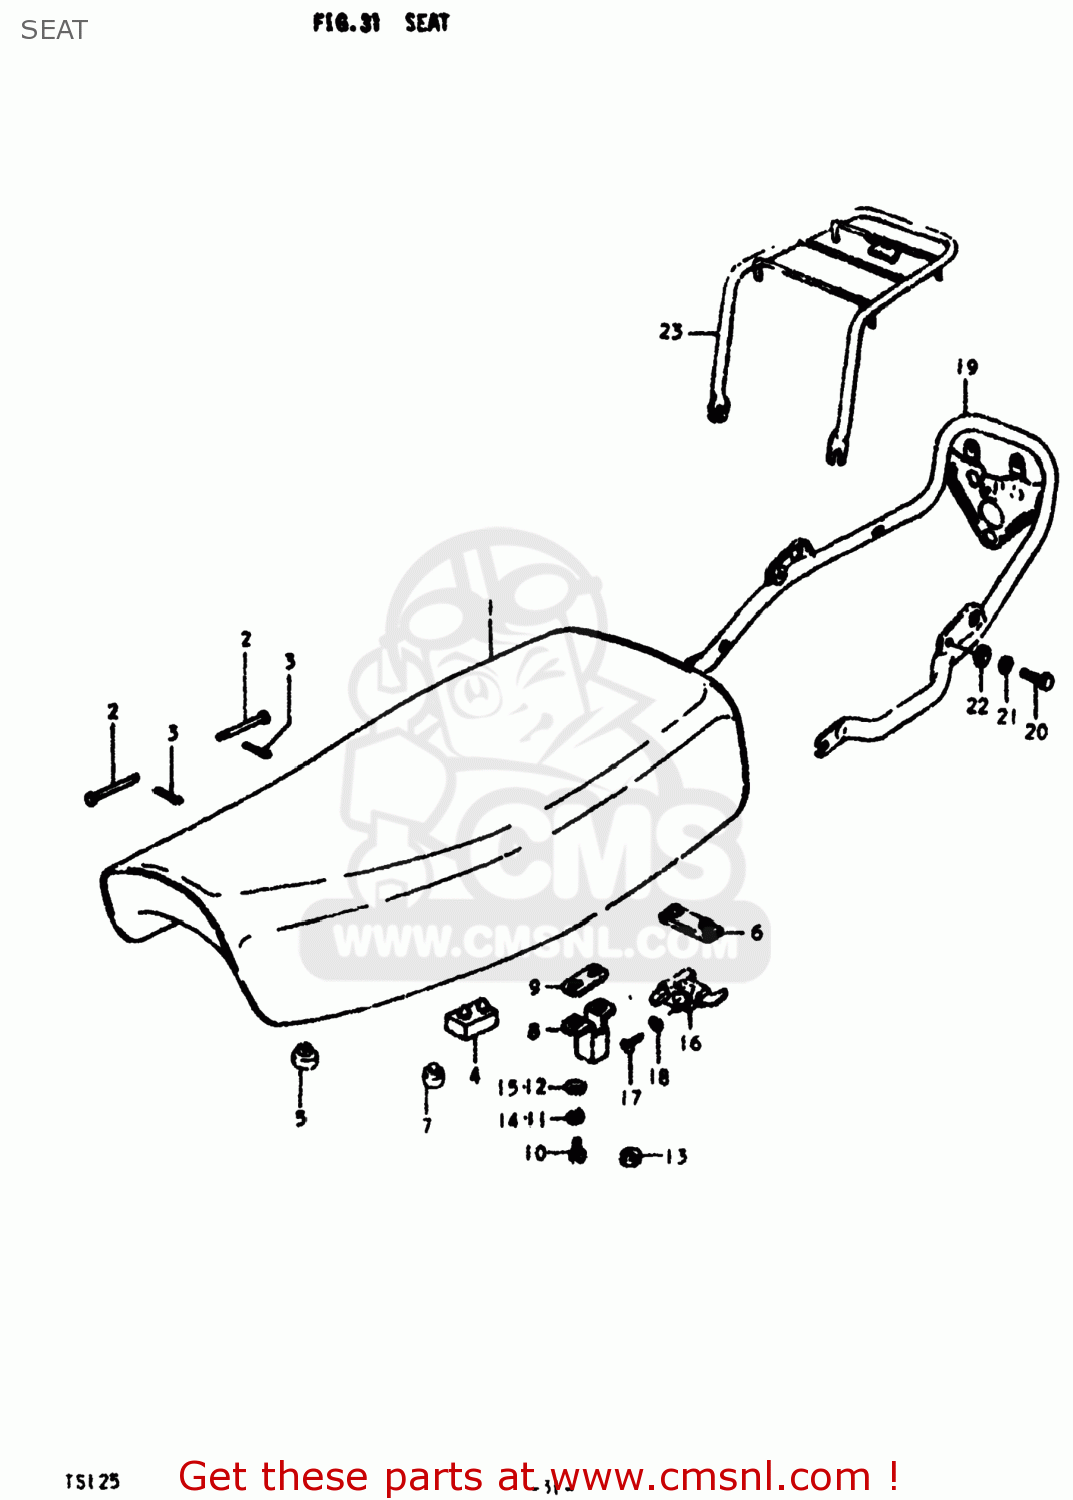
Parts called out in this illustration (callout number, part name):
1	SEAT ASSEMBLY
2	PIN
3	PIN
4	CUSHION
5	CUSHION(11.5X22X20)
6	CUSHION
7	CUSHION
8	PLATE,CLAMP GUIDE
9	WASHER(8X22X1)
10	BOLT
11	LOCK WASHER
12	WASHER
13	NUT
14	LOCK WASHER
15	WASHER
16	LOCK ASSY,SEAT
17	SCREW
18	LOCK WASHER
19	BRACKET,REAR TURN SIGNAL
20	BOLT
21	LOCK WASHER
22	WASHER
23	CARRIER
